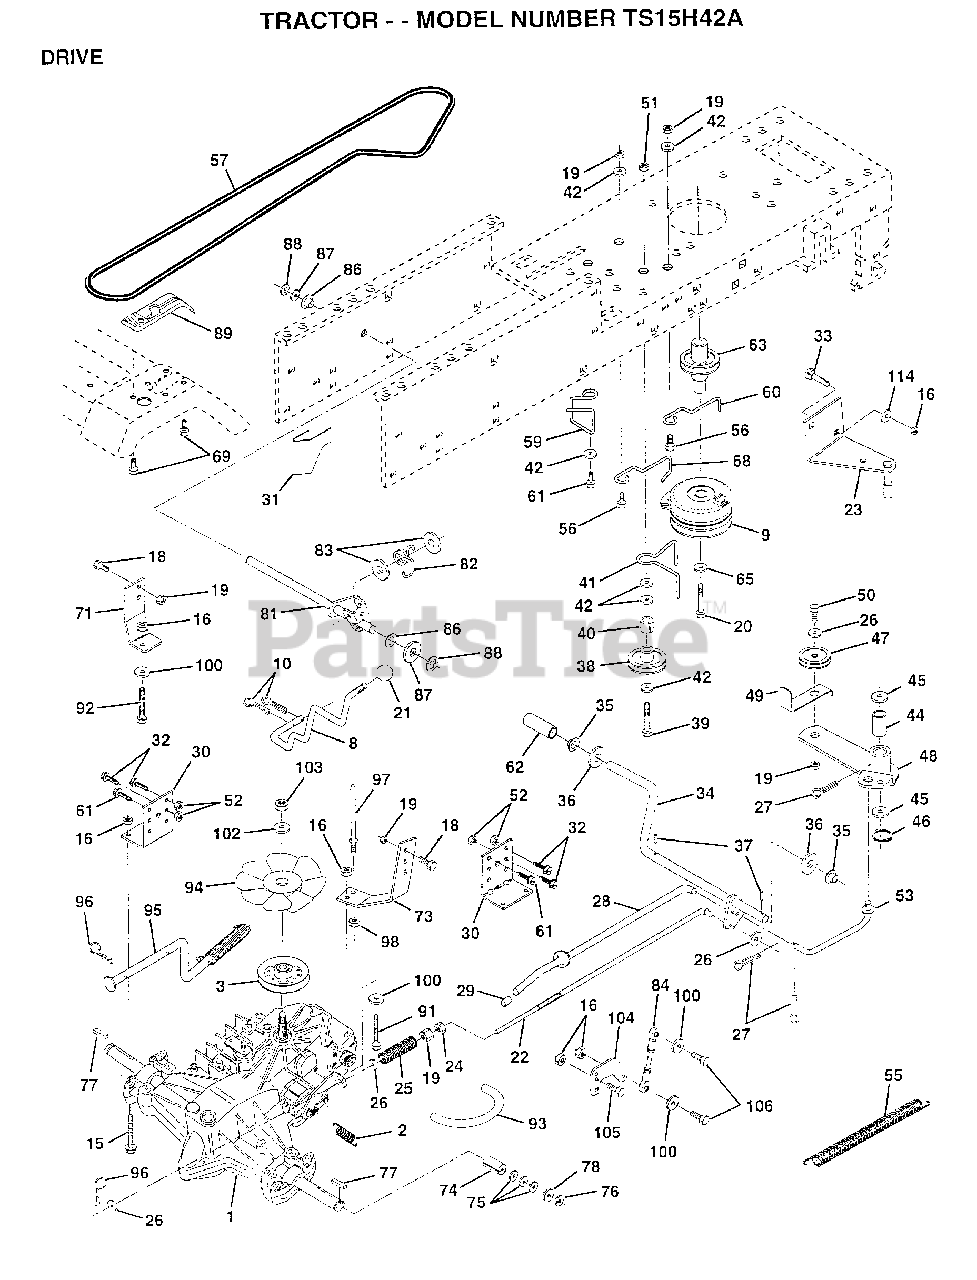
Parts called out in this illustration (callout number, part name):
1	TRANSAXLE.3100650
2	SPRING RET BRAKE
3	PULLEY.TRANSAXLE
8	ROD SHIFT FEND YT
9	CLUTCH.ELECT.EVX.
10	PIN COTTER 1/8
15	BOLT.HX.FLG.5/16
16	NUT
18	BOLT
19	NUT
20	BOLT.7/16-20X4.25
21	KNOB T (1/2-HOLE)
22	ROD.BRAKE.HYDRO.
23	BRACKET.CLU.MTG
24	NUT
25	SPRING ROD LT
26	WASHER
27	COTTER PIN
28	ROD.BRAKE.PARK.LT
29	PLUNGER CAP T
30	TRANSAXLE MTG BKT
31	"KEEPER,BELT LH T"
32	BOLT
33	BOLT
34	SHAFT FOOT PEDAL
35	NYLON BEARING
36	WASHER LT
38	PULLEY.IDLER.FLAT
39	BOLT
40	SPACER T
41	KEEPER BELT
42	WASHER
44	"LY, BEARING"
45	WASHER LT
46	KLIP RING
48	ARM IDLER
49	RETAIN BELT
53	"LINK, CLUTCH T"
55	"SPRING, RETURN LT"
57	"BELT.GD DRV 82"""
59	KEEPER BELT CNTSP
60	KEEPER BELT ENGLH
61	SCREW
62	PEDAL COVER T
63	PULLEY.CLUTCH.EVX
65	LOCKWASHER
68	"KEEPER,BLT ENG LT"
69	SCREW HEXWSH H-L
71	STRAP TORQ LH HYD
73	STRAP TORQ RH HYD
74	SPACER SPLIT
75	WASHER
76	E-RING LT
77	SQUARE KEY
78	WASHER
82	"SPRING,TORSION"
83	WASHER
84	ROD.TIE.BALL.4.75
86	BUSHING
87	WASHER D
88	KLIP RING
92	HEX BOLT
93	"LINE FUEL HYD 4"""
94	"FAN 7"" HYDRO"
96	RETAINER M
97	BOLT KEEPER RH
98	NUT
100	WASHER M
102	WASHER BELLEVILLE
104	ARM CONTROL HYDRO
105	SCREW CAP 5/16-18
106	BOLT
114	WASHER
